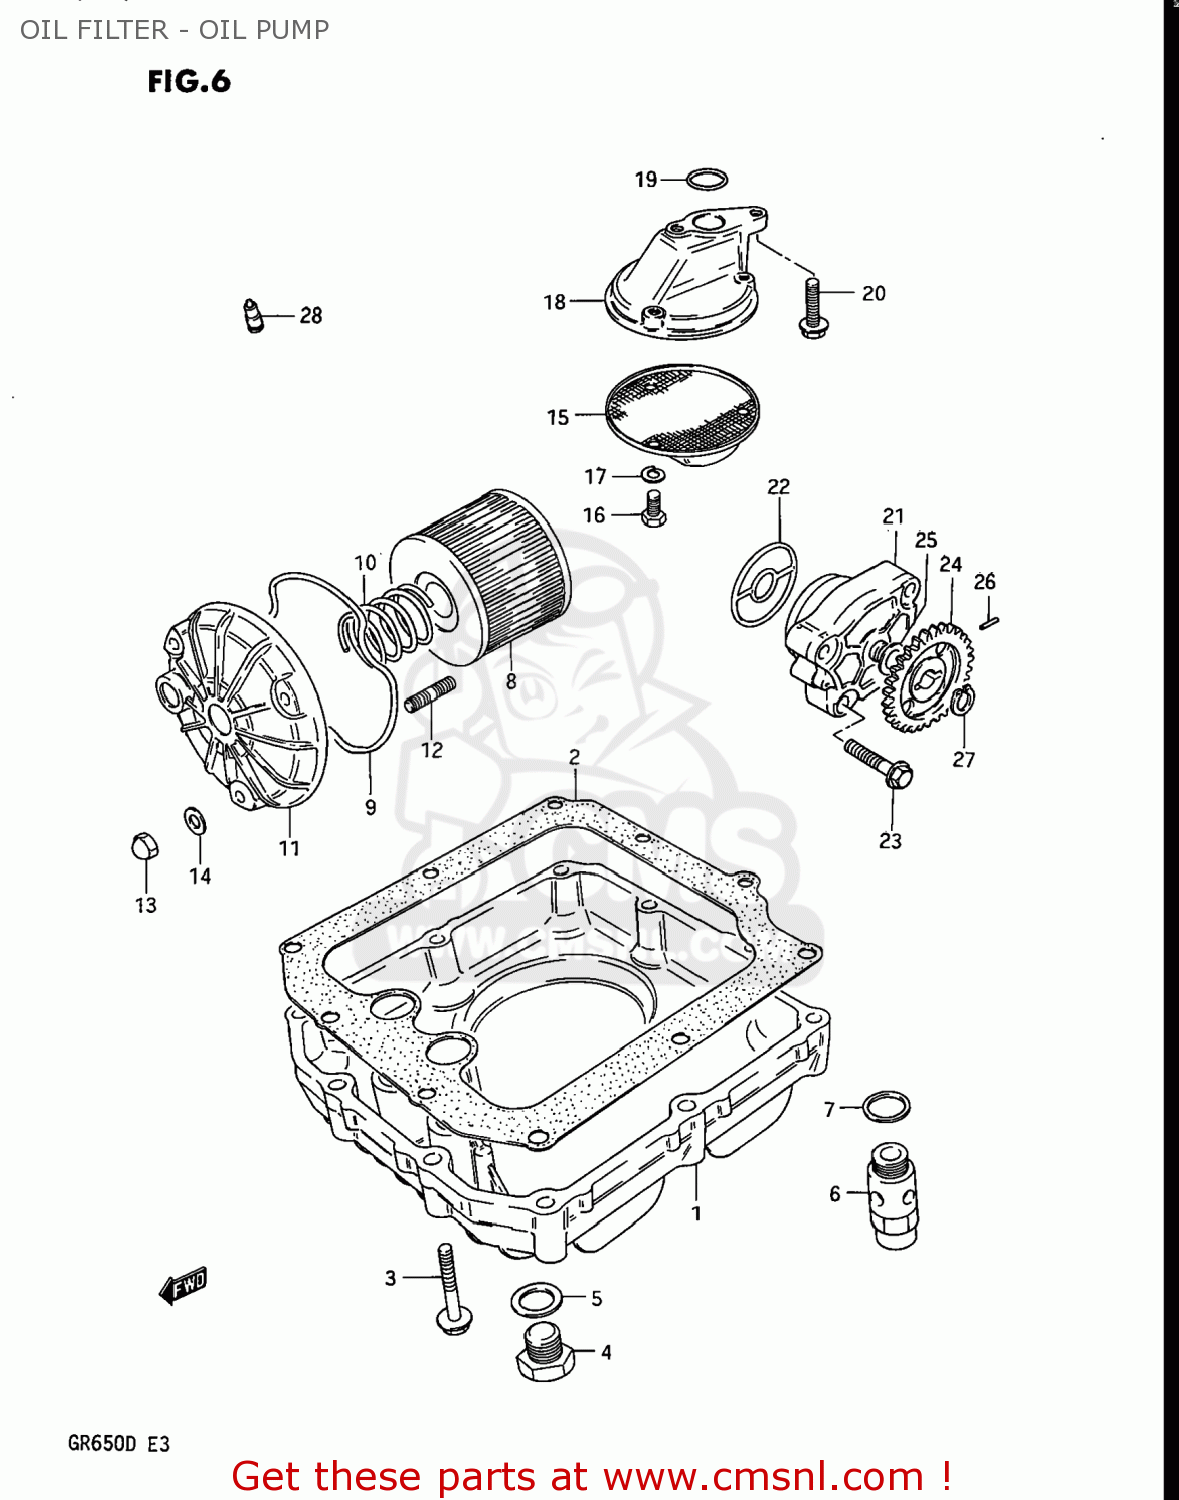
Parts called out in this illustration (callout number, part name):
1	PAN,OIL
2	GASKET,OIL PAN (MCA)
3	BOLT 6X30
4	PLUG
5	GASKET(14X19.2X2) (NAS)
6	REGULATOR ASSEMBLY,ENGINE
7	WASHER
8	FILTER ASSY,ENGINE OIL
9	O RING,OIL FILTER CHAMBER CAP
10	SPRING
11	CAP,OIL FILTER
12	STUD 6X20
13	NUT 6MM
14	WASHER
15	STRAINER,ENGINE OIL
16	BOLT
17	LOCK WASHER
18	PROTECTOR,OIL STRAINER
19	O RING(D:3.2,ID:15.8)
20	BOLT,REAR
21	PUMP ASSEMBLY,ENGINE OIL
22	O-RING,OIL PUMP
23	BOLT
24	GEAR,OIL PUMP DRIVEN (N
25	SHIM
26	PIN(4X15.8)
27	CIRCLIP
28	VALVE ASSEMBLY,PISTON OIL
